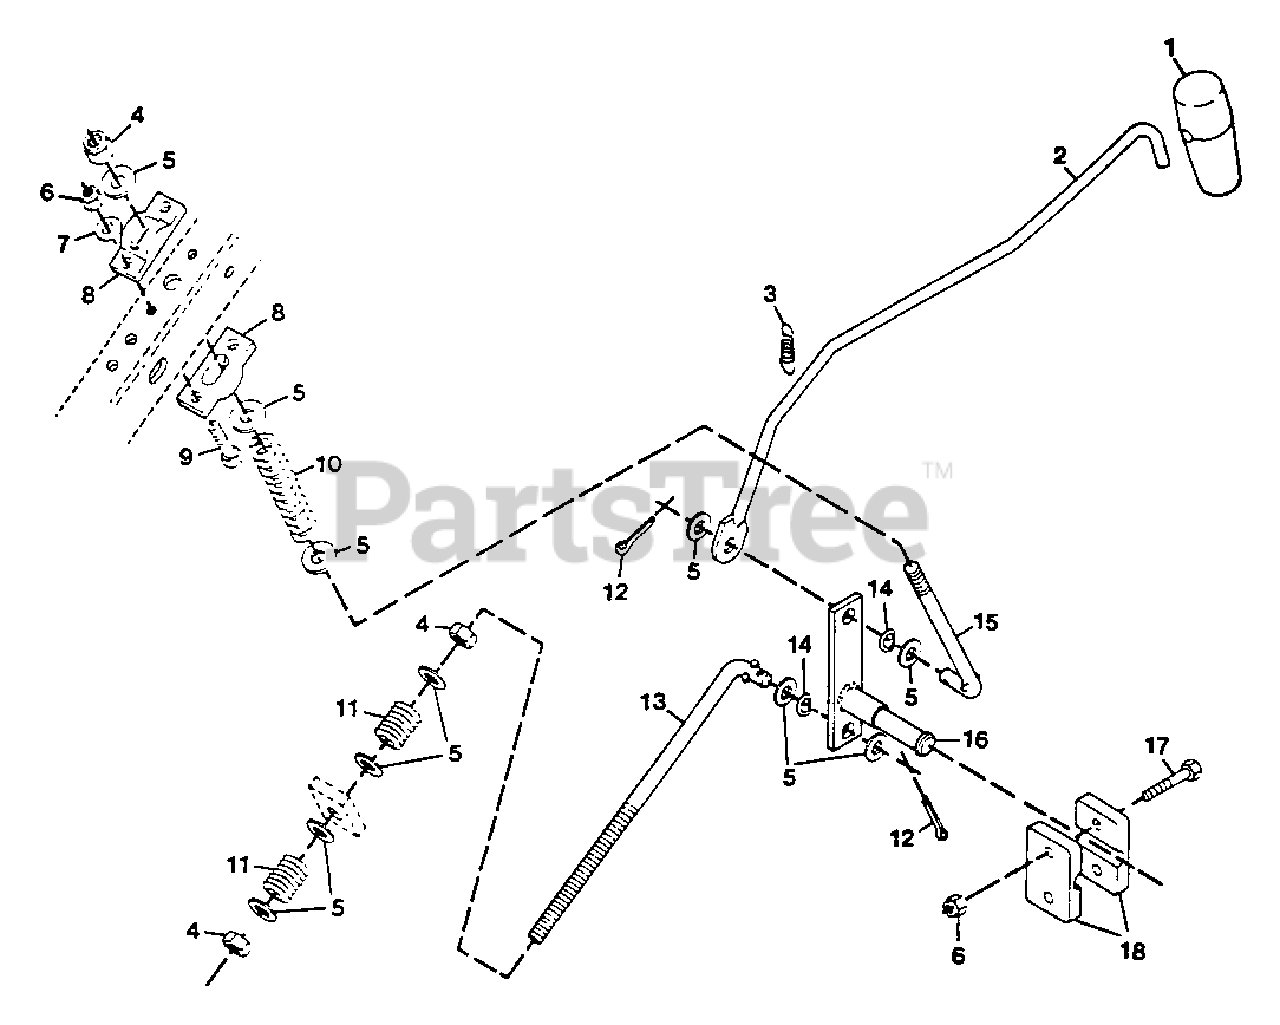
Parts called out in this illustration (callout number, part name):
1	Handle, Rubber Shifter
2	Rod, Shifter
3	Spring, Extension .50x1.25
4	Nut, Lock 3/6-16
5	Washer, Flat .406x.812x.065
6	Nut, Lock 1/4-20
7	Washer, Flat .281x.625x.065
8	Cam, Shifter
9	Bolt, Hex 1/4-20x1.00
10	Spring, Comp. .720x2.75
11	Spring, Comp. 1x.78x338
12	Pin, Cotter .125x.750
13	Link, Shifter
14	Washer, Spring .375 I.D.
15	Weldment, Shifter Crank
16	Link, Shifter Stop
17	Bolt, Hex 1/4-20x1.50
18	Block, Shift Lever
